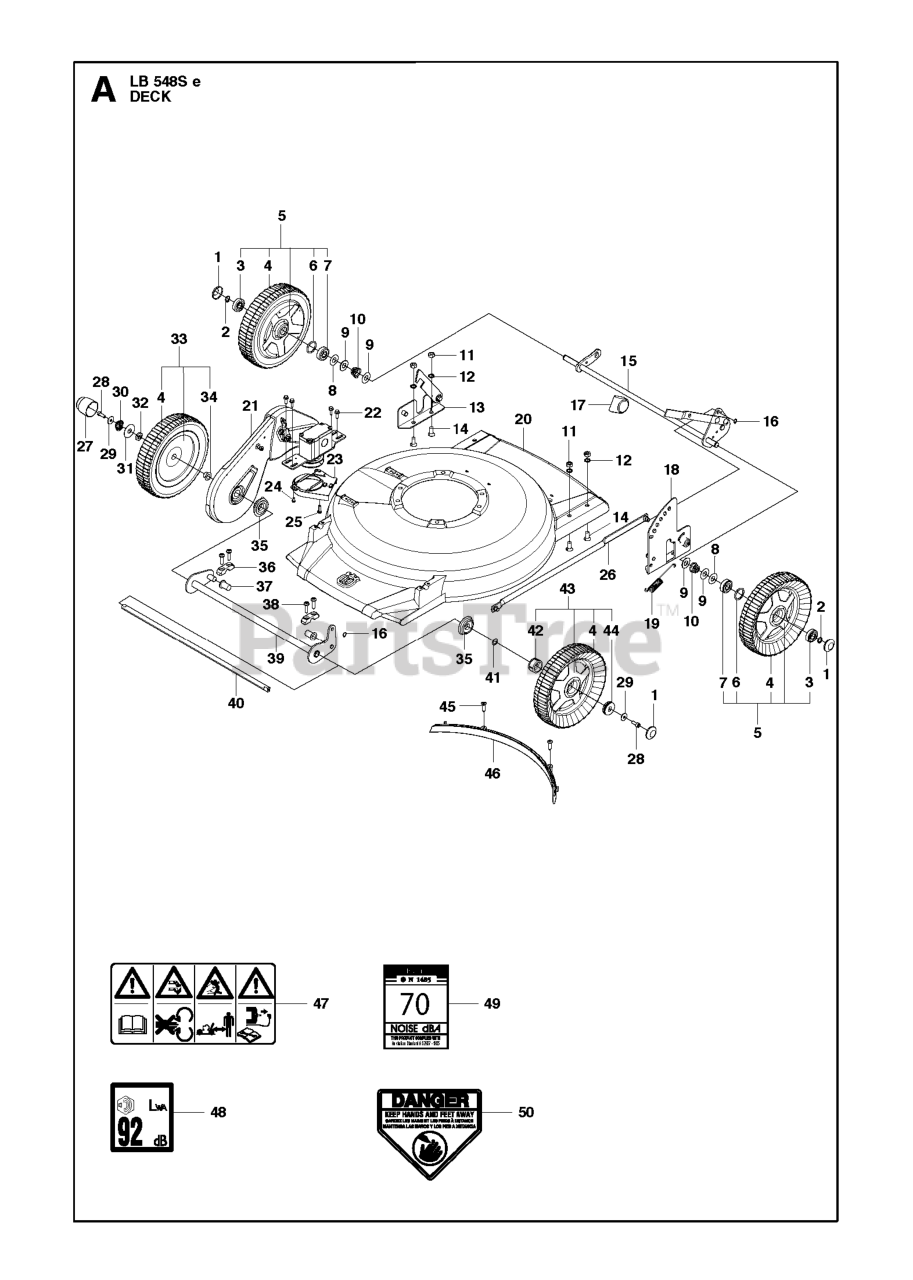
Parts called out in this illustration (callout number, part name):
11	NUT
16	RETAINING RING SGA 8
50	LABEL, DANGER
